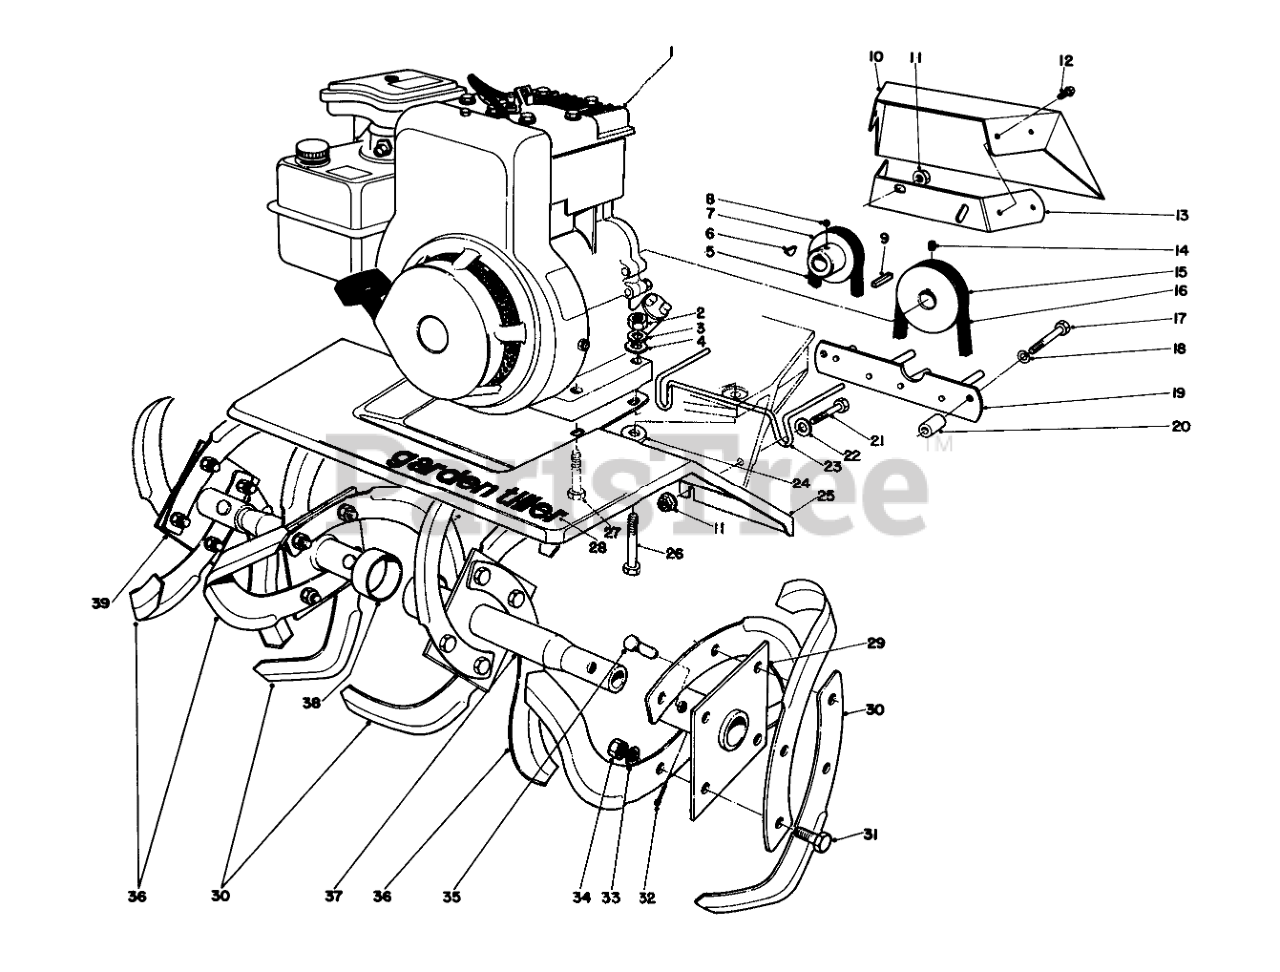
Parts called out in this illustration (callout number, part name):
1	Engine
2	NUT-HEX
3	WASHER-LOCK
4	WASHER-PLAIN
5	V-Belt Rev.
6	HI PRO KEY
7	Pulley-Engine Rev.
8	SCREW-HSH
9	KEY-SQUARE
10	PULLEY GUARD
11	NUT-LOCK, HHF
12	SCREW-HWHTF
13	Strap-Belt Shield
14	Screw-Set
15	Pulley & Engine (Fwd.)
16	V-Belt (Fwd.)
17	SCREW-HH
18	WASHER-LOCK
19	Belt Guide
20	Spacer
21	SCREW-HH
22	WASHER-FLAT
23	Belt Guide-Worm Shaft
24	WASHER-FLAT
25	TINE SHROUD
26	SCREW-HH
27	SCREW-HH
28	Decal
29	Axle L.H.Outer
30	RH TINE
31	SCREW-HH
32	PIN-COTTER
33	WASHER-LOCK
34	NUT-HEX
35	TINE PIN
36	LH TINE
37	Axle L.H. Inner
38	Axle R.H. Inner
39	Axle R.H. Outer
